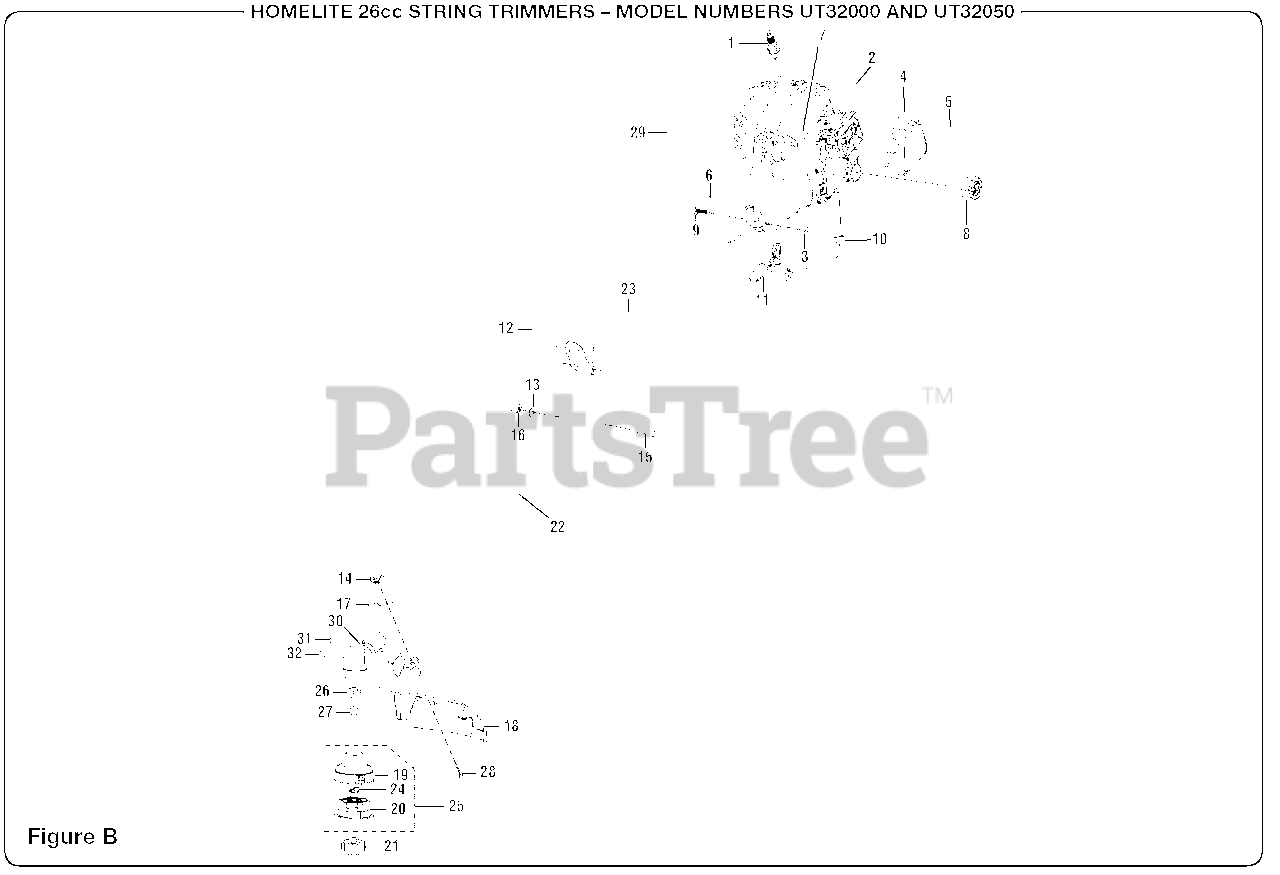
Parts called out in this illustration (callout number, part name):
1	Spark Plug (Champion RCJ6Y)
2	Logo Label
3	Hex Nut (M6)
4	Air Box Cover
5	Starting Label
6	Screw (8-16 x 5/16 in.)
7	Switch
9	Bolt (M6 x 20 mm)
10	Throttle Cable
11	Throttle Trigger
13	Washer (1/4-20)
14	Wing Nut (1/4-20)
15	Bolt (1/4-20 x 45 mm)
16	Wing Nut (1/4-20)
17	Mounting Bracket
18	Straight Shaft Grass Deflector (Incl. Key Nos. 14, 17, and 28)
19	Large String Head Housing
20	Dual Line Spool and String (0.080 in.)
21	Spool Retainer
22	Boom Assembly Incl. Key Nos. 26, 27, 31 and 32)
23	Warning Label
24	Spring
25	String Head Assembly (Incl. Key Nos. 19-20 and 24)
26	Flanged Washer
28	Square Bolt (1/4-20 x 1 in.)
29	Combusion Warning Label
30	Gear Head
31	Bolt (1/4-20 x 1-1/4 in.)
32	Screw (10-24 x 5/8 in.)
